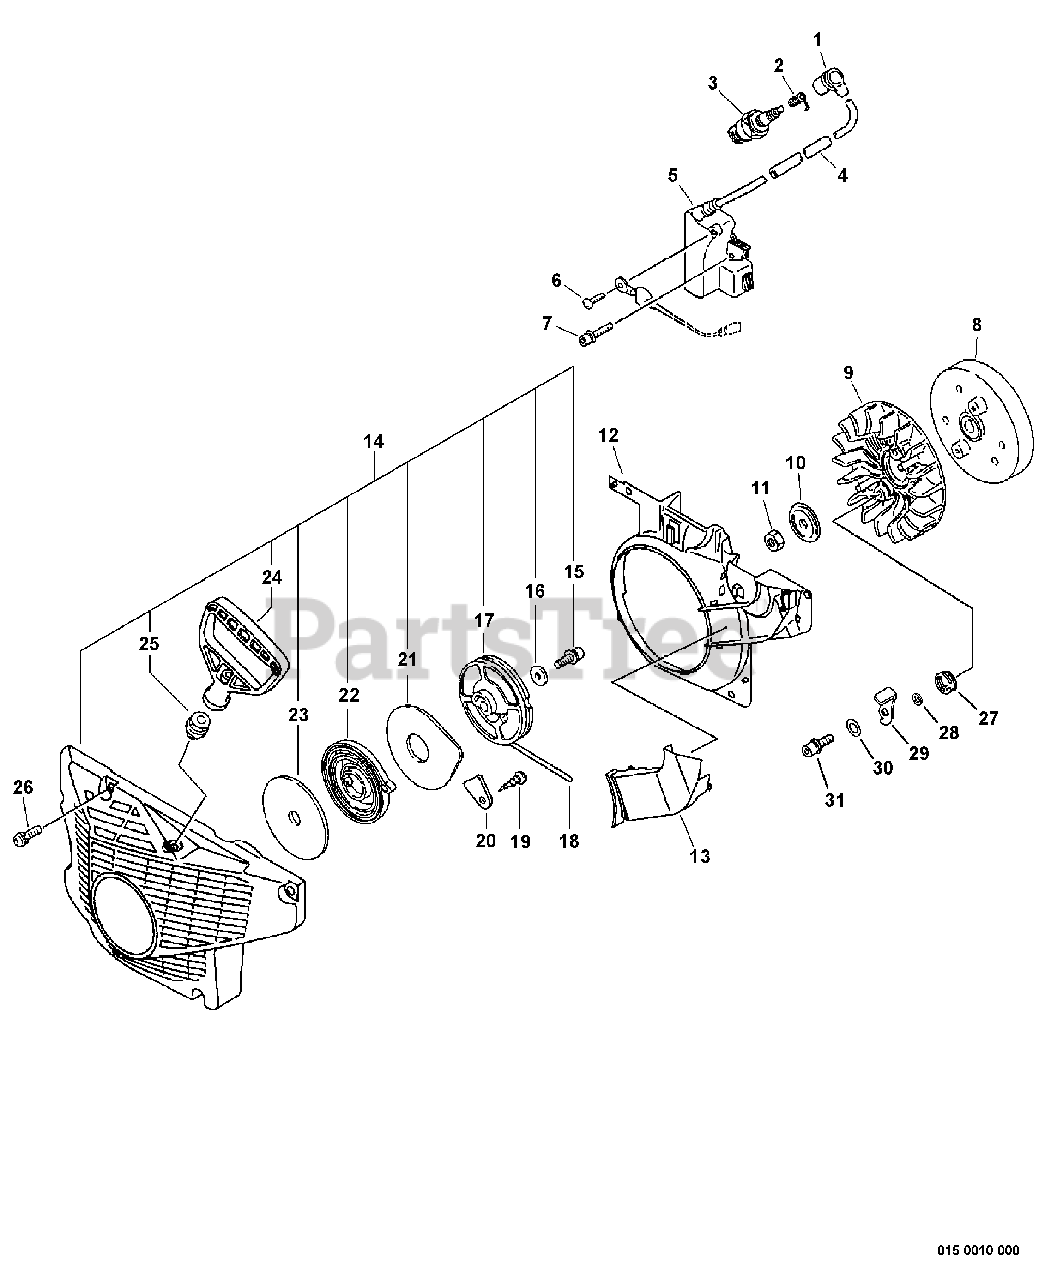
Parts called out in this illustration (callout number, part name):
1	CAP, SPARK PLUG
2	TERMINAL, SPARK PLUG CAP
3	SPARK PLUG -- BPM-7A
3	SPARK PLUG -- BPMR-7A
5	COIL, IGNITION
6	SCREW - 4X8
7	SCREW - 4X20
8	FLYWHEEL
10	WASHER - CUP
12	COVER, FAN
13	DUCT, AIR
14	STARTER ASSY
15	SCREW - 5X14
16	WASHER - 5
17	REEL, ROPE
18	ROPE, STARTER - 4X950
19	SCREW - 4X8
20	RETAINER, BRAKE BAND
21	PLATE, STARTER
22	SPRING, REWIND
23	PLATE, STARTER
24	GRIP, STARTER
25	GUIDE, ROPE
26	SCREW - 5X20
27	SPRING, RETURN
28	SPACER, PAWL
29	PAWL, STARTER
30	WASHER - 5
31	SCREW - 5X20
